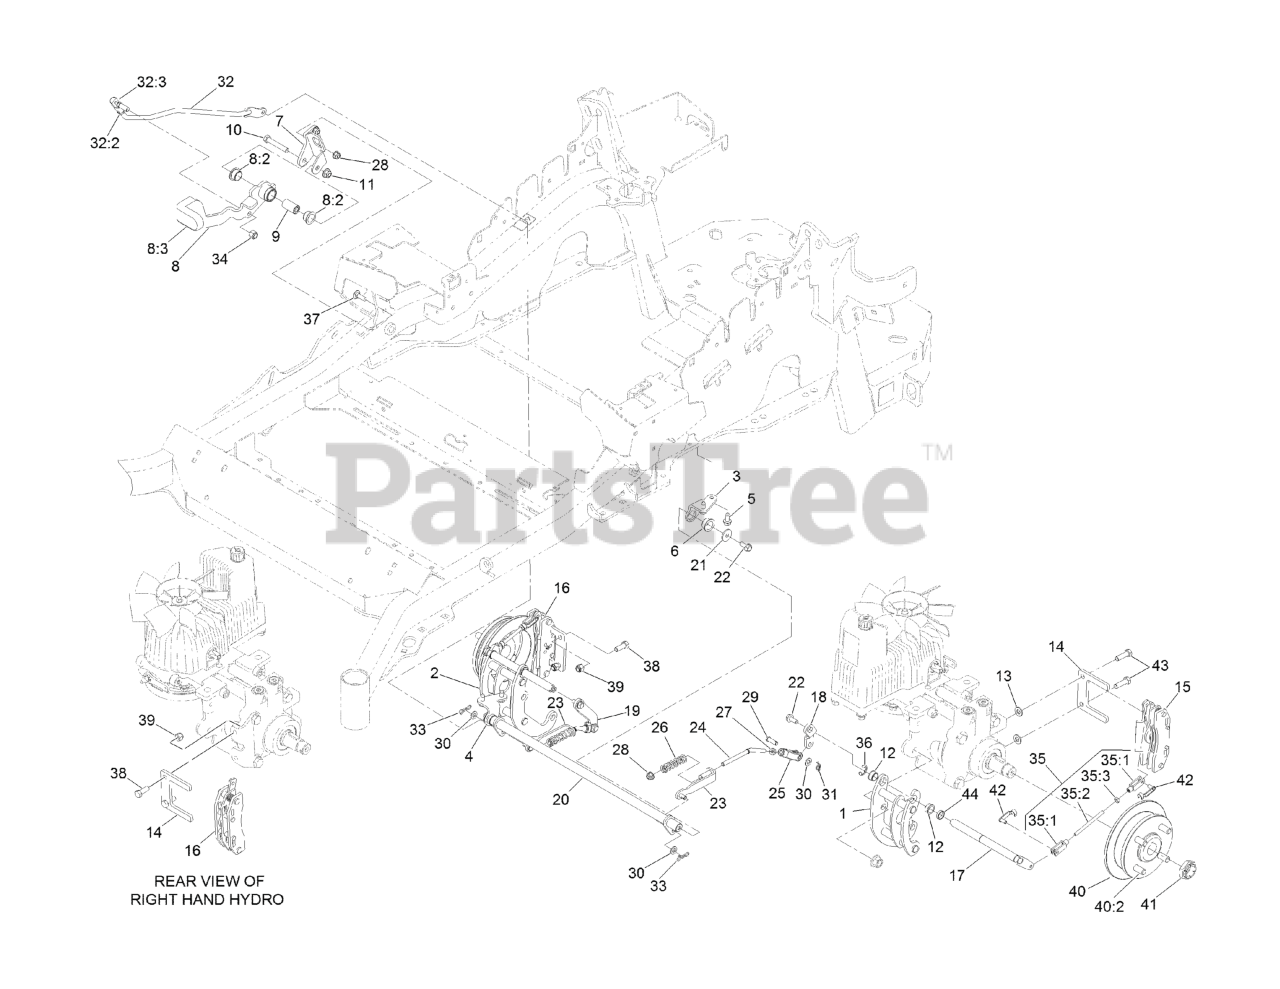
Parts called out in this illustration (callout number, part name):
1	MOUNT-BELLCRANK, LH
2	MOUNT-BELLCRANK, RH
3	MOUNT-PIVOT, LH
4	MOUNT-PIVOT, RH
5	Screw-HWH 5/16-18 X 3/4 Tf
6	BUSHING-FLANGE
7	BRACKET-MOUNT
8	BRAKE LEVER ASM W/ GRIP
8:2	BUSHING-FLANGE
8:3	GRIP-LEVER
9	HANDLE-PIVOT, BRAKE
10	SCREW-HH
11	NUT-HF, NI
12	BUSHING
13	WASHER-FLAT
14	PLATE-MOUNT, BRAKE
15	CALIPER-BRAKE
16	CALIPER-BRAKE, RH
17	BELLCRANK
18	ARM-INNER, LH
19	ARM-INNER, RH
20	SHAFT-CROSS
21	WASHER-FLAT
22	SCREW-HHF
23	BRACKET-L
24	LINKAGE-MID
25	YOKE-OFFSET
26	SPRING-COMPRESSION
27	NUT-JAM
28	NUT-HF, NI
29	PIN-CLEVIS
30	WASHER-PLAIN
31	PIN-COTTER, LOCKING
32	FRONT LINKAGE ASM
32:2	END-TIE ROD, RH
32:3	NUT-HJ
33	PIN-COTTER, LOCKING
34	NUT-LOCK
35	REAR LINKAGE ASM
35:3	NUT-JAM
37	BOLT-CARR
38	SCREW-HH
39	NUT-LOCK, NI
40	WHEEL HUB ASM
40:2	STUD-WHEEL
41	LOCKNUT
42	PIN-CLEVIS, SPRING
43	SCREW-LOCK, PATCH
